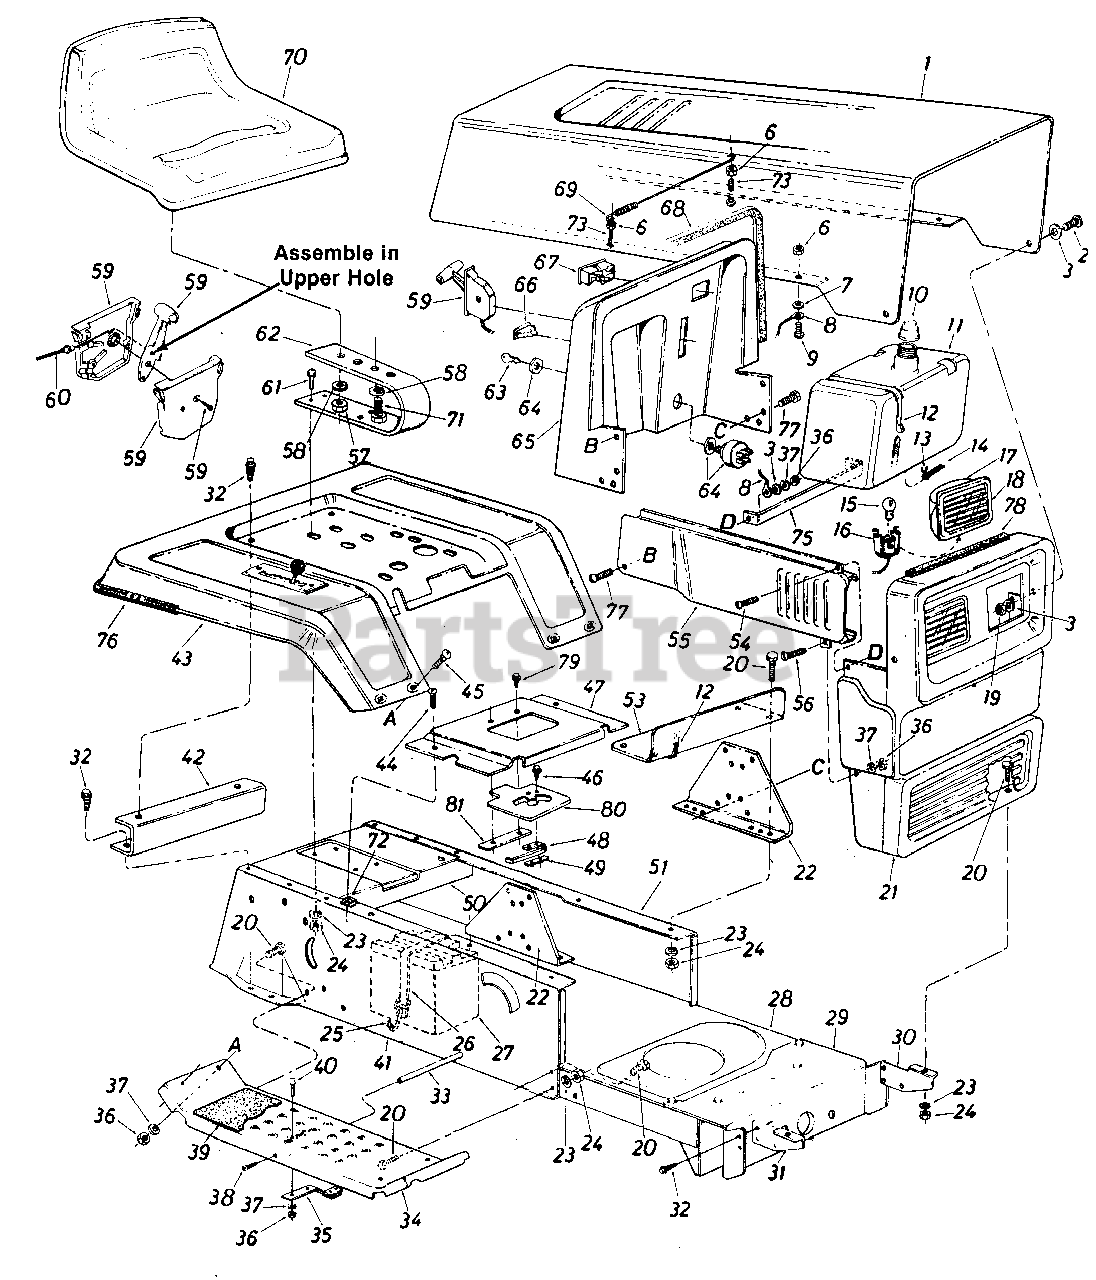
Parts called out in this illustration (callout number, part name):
1	Hood
2	Hex Scr. 1/4-20 x .62" Lg.
3	Fl-Wash. .296" I.D. x .62"O.D.
6	Hex Sems Nut #10-24 Thd.
7	Fl-Wash. .203" I.D. x .41" O.D. x .040
8	Hood Stop
9	Truss Hd. Scr. #10-24 x 1/2" Lg.
10	Fuel Cap Gauge
11	Fuel Tank
12	Tie Strap
13	Hose Clamp
14	Fuel Line
15	Lamp
16	Socket
17	Headlight Housing
18	Lens
19	Hex L-Nut 1/4-20 Thd.
20	Hex Bolt 5/16-18 x .75" Lg.
21	Grille
22	Dash Support Bracket
23	L-Wash. 5/16" I.D.
24	Hex Nut 5/16-18 Thd.
25	Battery Strap Hook
26	Battery Hold Down Strap
27	12V-Battery
28	Lower Frame
29	Front Pivot Brk't.
30	Grille Mount Brk't.-L.H.
33	Running Board Rod
34	Running Board
35	Blade Brake Ass'y.
36	Hex Nut 1/4-20 Thd.
37	L-Wash. 1/4" I.D.
38	Truss Mach. Scr. 5/16-18 x .75" Lg.
39	Foot Pad
40	Carriage Bolt 1/4-20 x .62" Lg.
41	R.H. Side Frame
42	Fender Mount Brace
43	Rear Fender
45	Carriage Bolt 1/4-20 x .50" Lg.
46	Truss Hd. Scr. #10-24 x .50" Lg.
47	Transrnission Panel
48	Reverse Safety Switch
49	Insulator Nut Plate
50	Hitch Plate
51	L.H. Side Frame
53	Fuel Tank Support
54	Truss Hd. Scr. 1/4-20 x .75" Lg.
55	Side Cover-R.H.
56	Truss Mach. Scr. 1/4-20 x .50" Lg.
57	Hex Nut 1/2-13 Thd.
58	L-Wash. 1/2" I.D.
59	Throttle Control Box Ass'y.
60	Throttle Control Wire
61	Hex Bolt 5/16-18 x 1.00" Lg.*
62	Seat Spring 5.5" High
63	Ignition Key
64	Ignition Switch
65	Dash Panel
66	Light Switch
67	Ammeter
68	Trim Strip-27"
69	Hood Spring
70	Seat Ass'y.
71	Hex Bolt 1/2-13 x 1.0" Lg.
72	Speed Nut #10Z
73	Hex Scr. #10-24 x 1.0" Lg.
75	Tie Strap-Grille/Side Panel
76	Trim Strip-81"
77	Hex Wash. Hd. Tap Scr. 1/4 x .75" Lg.
78	Foam Strip 3/8 x 1 x 14" Lg.
79	Truss Mach. Scr. 1/4-20 x .75" Lg.
80	Gear Selection Plate
81	Clamping Plate
